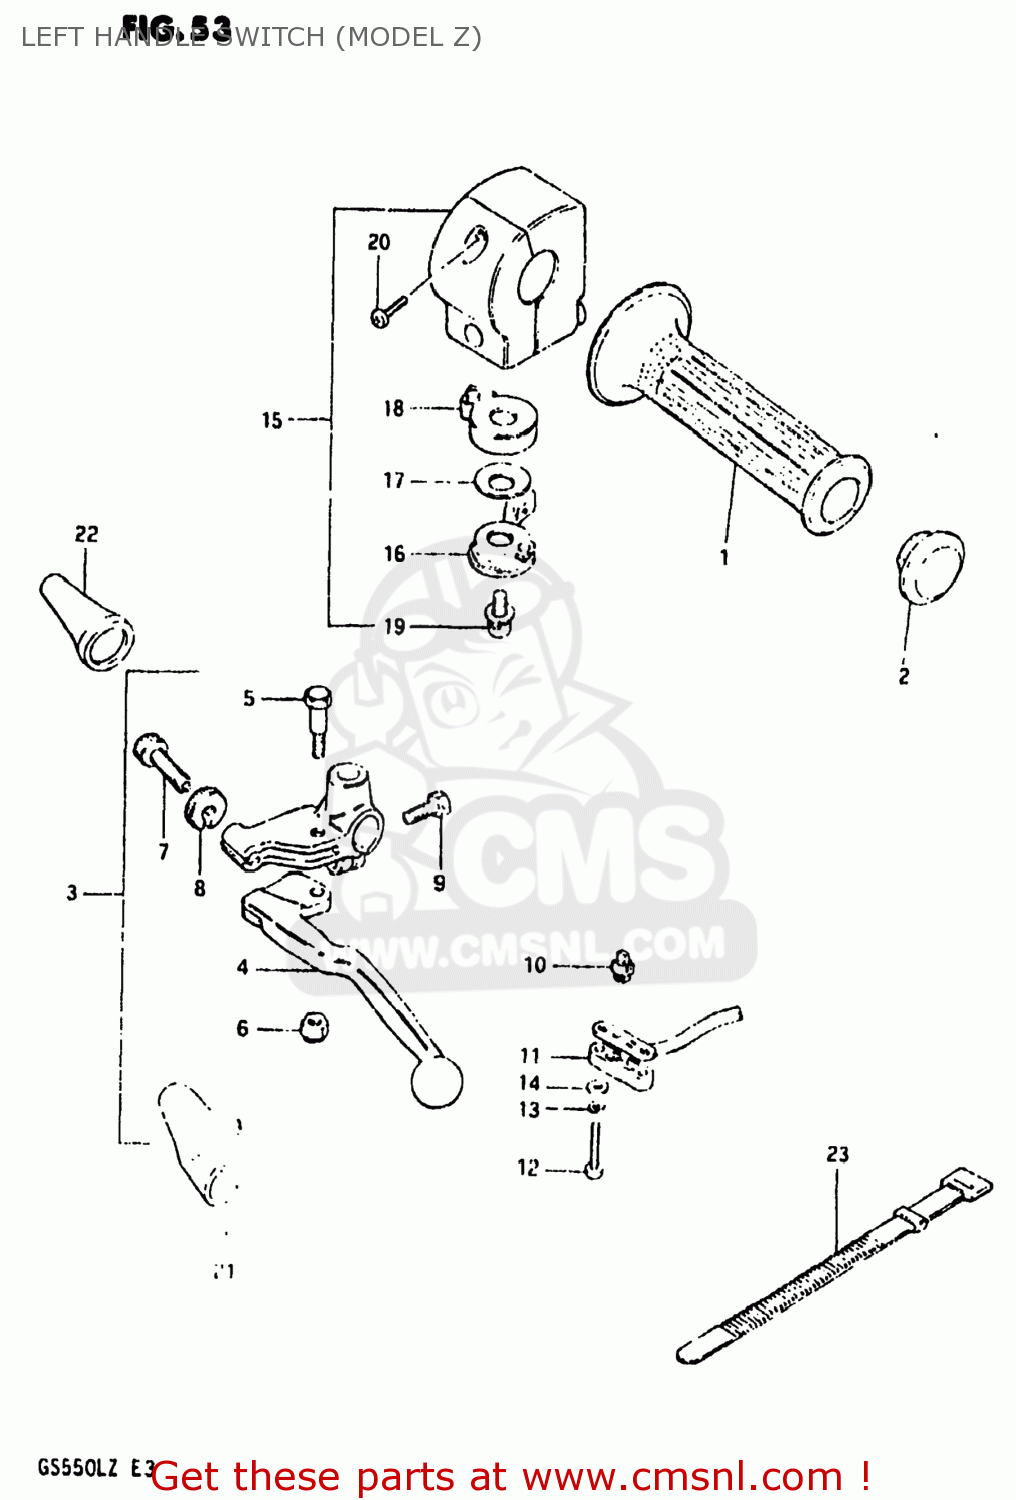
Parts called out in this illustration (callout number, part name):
1	GRIP,LEFT
2	CAP,GRIP END
3	LEVER ASSEMBLY
4	LEVER,CLUTCH
5	BOLT,LEVER
6	NUT 6MM
7	ADJUSTER,CABLE
8	NUT,CABLE ADJUSTER
9	BOLT,CLUTCH LEVER HOLDER
10	CONTACT,SWITCH
11	COVER,FR BK TERMINAL BASE
12	SCREW
13	LOCK WASHER
14	WASHER
15	SWITCH ASSEMBLY,HANDLE,LEFT
16	LEVER,STARTER
17	WASHER,ADJUSTER
18	BODY,CHOCK
19	SCREW,CHOKE LE
20	SCREW
21	COVER,CLUTCH LEVER
22	BOOT,CLUTCH CABLE
23	CLAMP(L:120)
